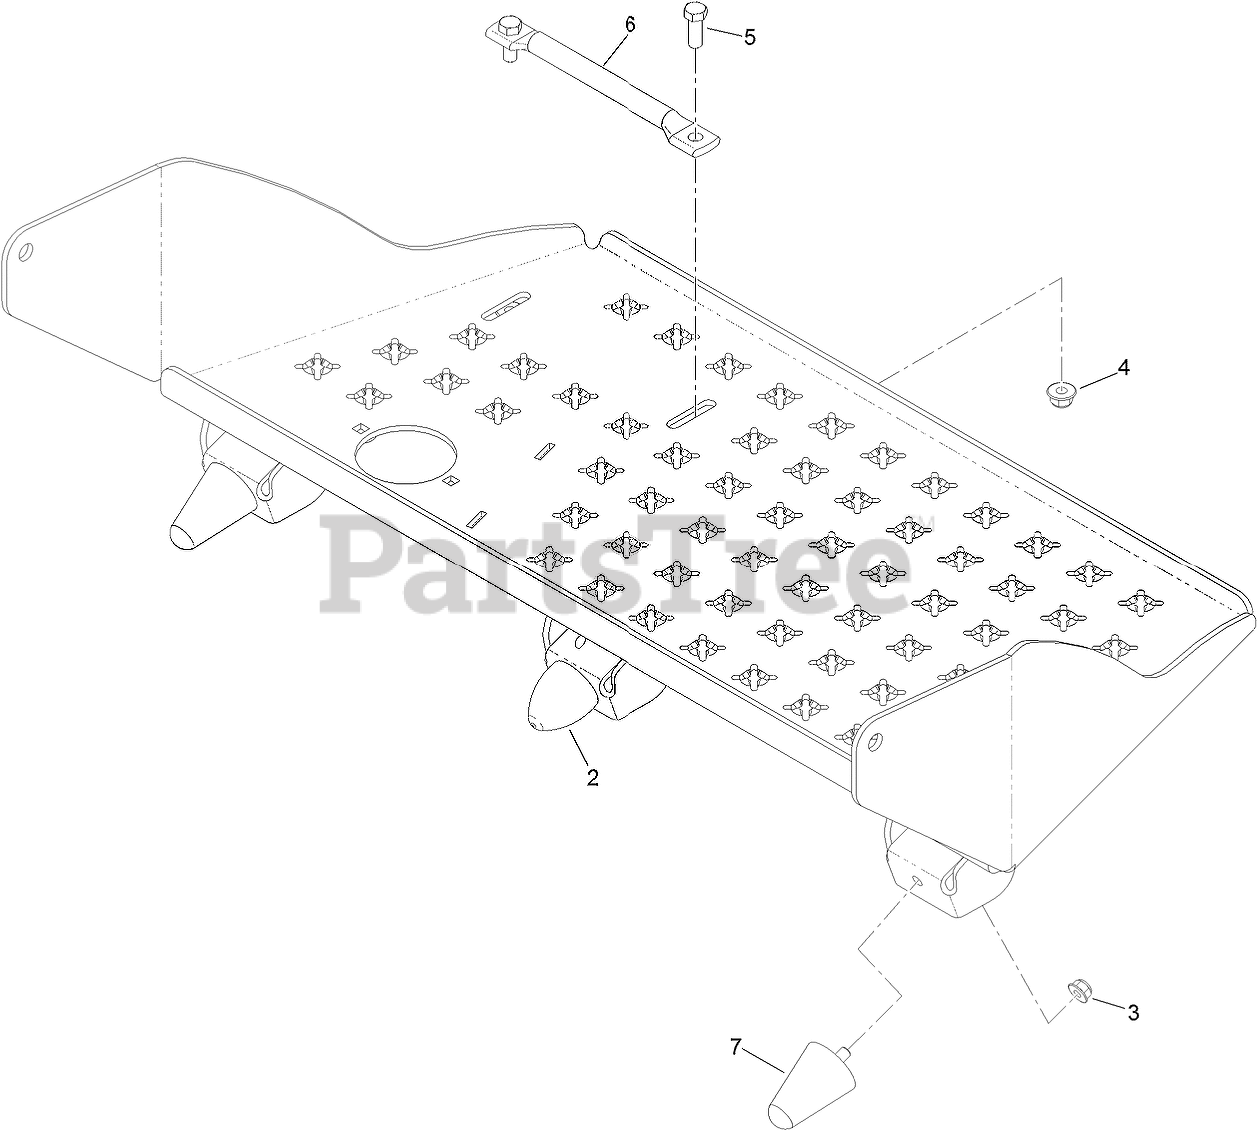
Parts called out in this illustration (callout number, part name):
2	BUMPER-RUBBER
3	NUT-HF, NI
4	NUT-HF, NI
5	SCREW-HH
6	ROCKER-PEDAL, FOOT
7	BUMPER-RUBBER
